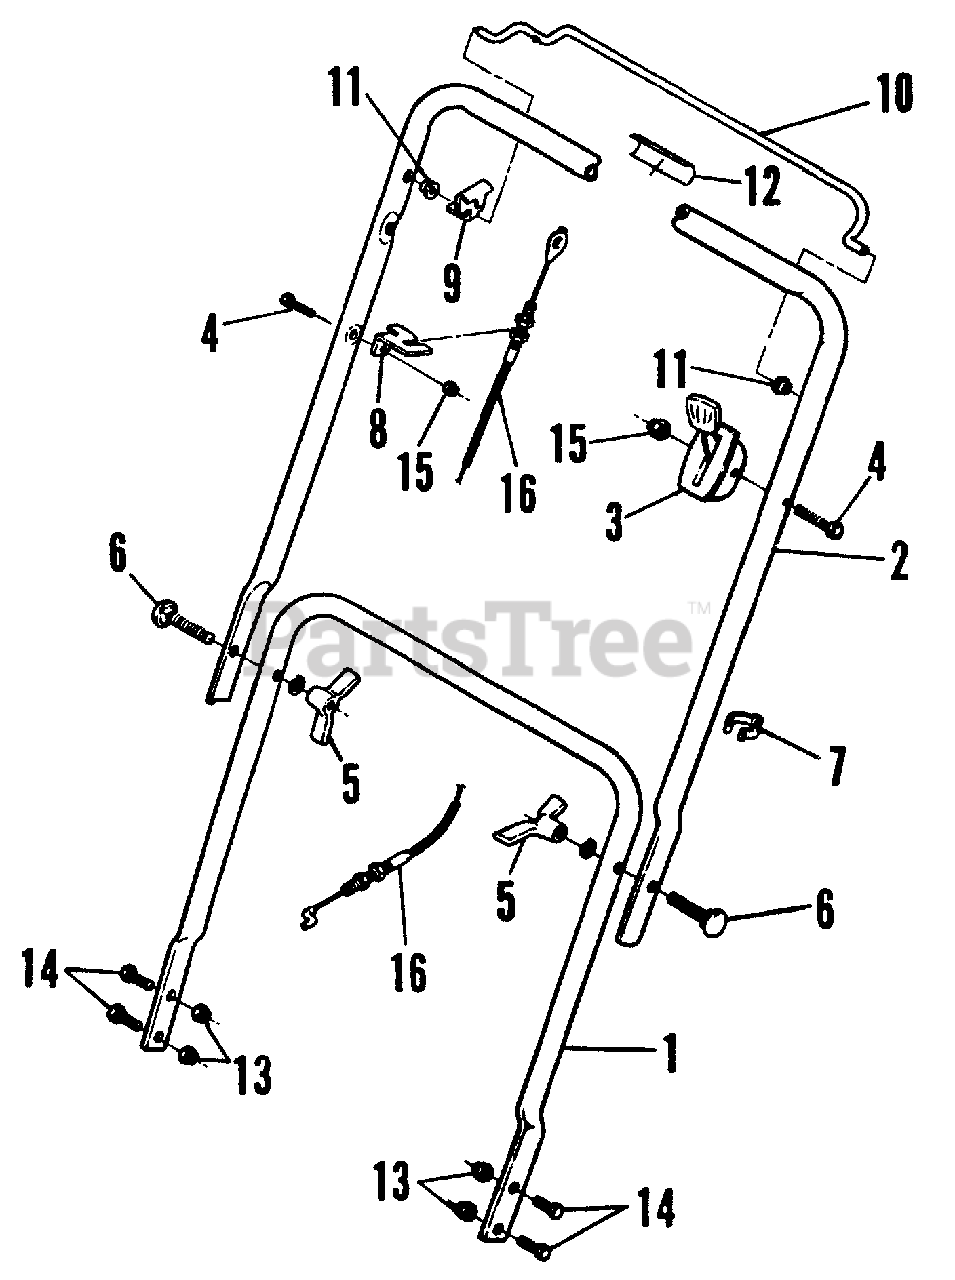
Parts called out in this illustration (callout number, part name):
1	LOWER HANDLE
2	UPPER HANDLE
3	CONTROL, Throttle
4	SCREW, 1/4-20 x 1-1/2" Hex Head Cap, Grade 5
6	BOLT, 5/16-18 x 2" Round Head Square Neck, Grade 5
7	CABLE CLIP, 7/8"
8	MOUNT, Cable
9	CATCH, Bail
10	BAIL
11	BUSHING, 5/16" I.D.
12	DECAL, Clutch Control
13	NUT, 3/8-16 Hex Nyloc
14	SCREW, 3/8-16 x 1" Hex Head Cap, Grade 5
15	NUT, 1/4-20 Hex Nyloc
16	CABLE, Drive 66.5"
